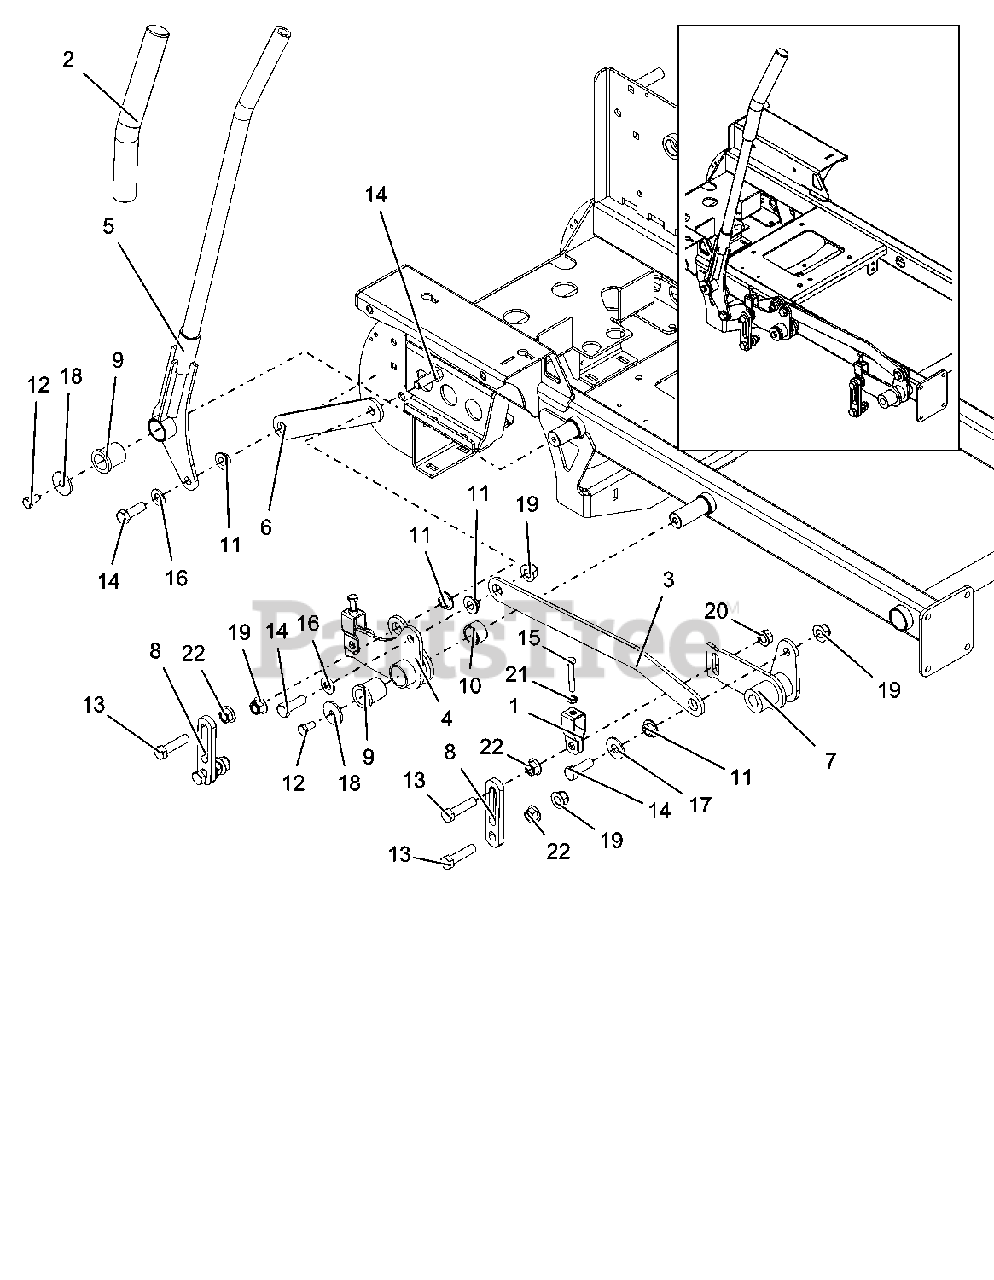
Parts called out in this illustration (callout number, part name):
1	BRKT, DECK LEVELING
2	GRIP, HANDLEBAR 1.00X1.38X11.3
3	PLATE, DECK ARM
4	WLDMT, REAR DECK ARM
5	WLDMT, DECK LIFT HANDLE
6	LINK, DECK LIFT HANDLE
7	WLDMT, RH FRONT DECK ARM
8	LINK-DECK LIFT - SHORT
9	BSHG-FLG 1.00X1.25X1.50X1.50
10	BUSH, SLV 1.00 X 1.25 X .75
11	BSHG, FLG .515X.750X.360X1.12
12	@BLT-HEX .38-16X.75 GR5 YWZC
13	@BLT-HEX .50-13X2.00 GR5 YWZC
14	@BLT-HEX .50-13X1.50 GR5 YWZC
15	BLT-HEX .312-18X2.00 FTH GR5YZ
16	@WSHR-FL-STL.531X1.06X.095YWZC
17	@WSHR-FL-STL.563X1.38X.109YWZC
18	WSHR-FL-STL .380X1.50X.125YWZC
19	@NUT-LK-NYL-FLG .50-13 YWZC
20	NUT-LK-CTR-FLG .50-13 YWZC
21	NUT- JAM .312-18 YWZC
22	NUT-SPNLK-FLG .50-13 YWZC
